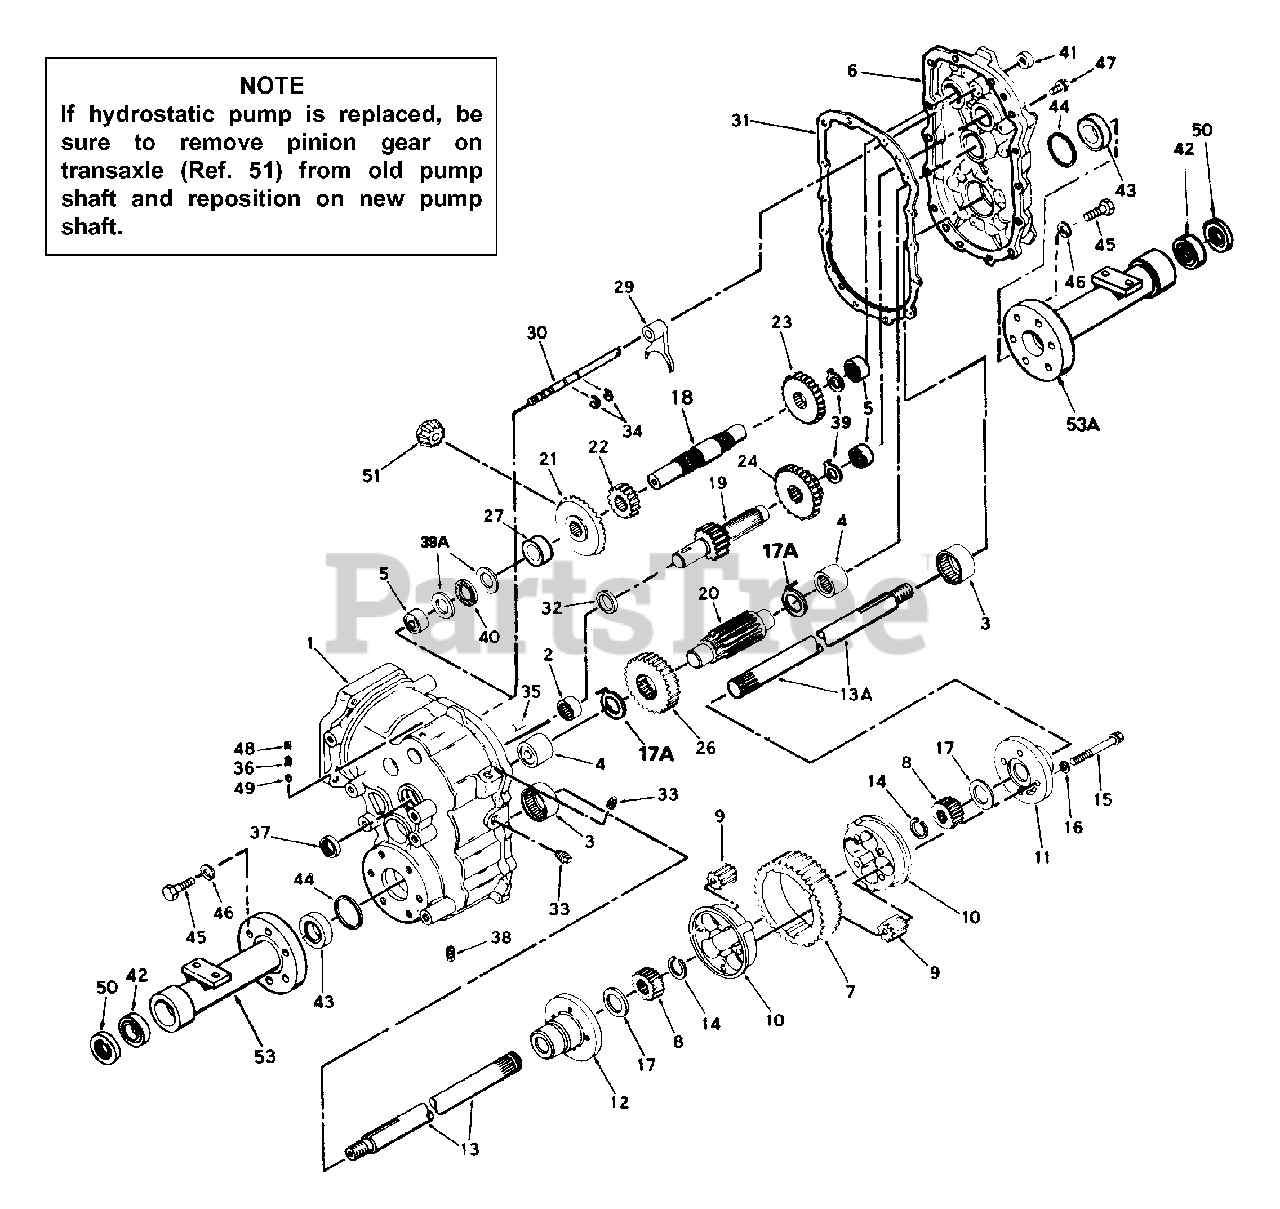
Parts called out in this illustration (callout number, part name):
1	Case Ass'y., Transaxle
2	Bearing, Needle
3	Bearing, Needle
4	Bearing, Needle
5	Bearing, Needle
6	Cover Ass'y., Transaxle
7	Gear, Ring
8	Gear, Side
9	Gear, Pinion
10	Core, Body
11	Carrier, Differential
12	Carrier, Differential
13	Axle, (18-17/64" Long)
13A	Axle, (15-29/64" Long)
14	Ring, Snap
15	Screw, Hex Hd. Mach., 3/8-16 x 3-3/8
16	Lock Washer, 3/8"
17	Washer, Thrust
17A	Washer, Thrust
18	Shaft, Counter
19	Shaft, Brake
20	Pinion, Output
21	Gear, Bevel (30 Teeth)
22	Gear, Spur (16 Teeth)
23	Gear, Spur (23 Teeth)
24	Gear, Cluster (20 and 27 Teeth)
26	Gear, Output (37 Teeth)
27	Spacer (55/64" Long)
29	Fork, Shift
30	Rod, Shift
31	Gasket, Case and Cover
32	Spacer
33	Plug, Pipe
34	Ring, Snap
35	Pin, Dowel
36	Spring
37	Seal, Oil
38	Plug, Magnetic Drain
39	Washer, Thrust
40	Bearing, Thrust
41	Seal, Oil
42	Bearing, Ball
43	Bearing, Thrust
44	Seal, Square Cut
45	Screw, Hex Hd. Mach.
46	Lock Washer, 1/2"
47	Screw, Hex Hd. Thd. Forming, 5/16-18 x 1
48	Screw, Set 1/4-20 x 1/2
49	Ball, Steel
50	Seal, Oil
51	Pinion, Bevel
53	Housing, Axle (9-1/4" Long)
53A	Housing, Axle (7-5/16" Long)
